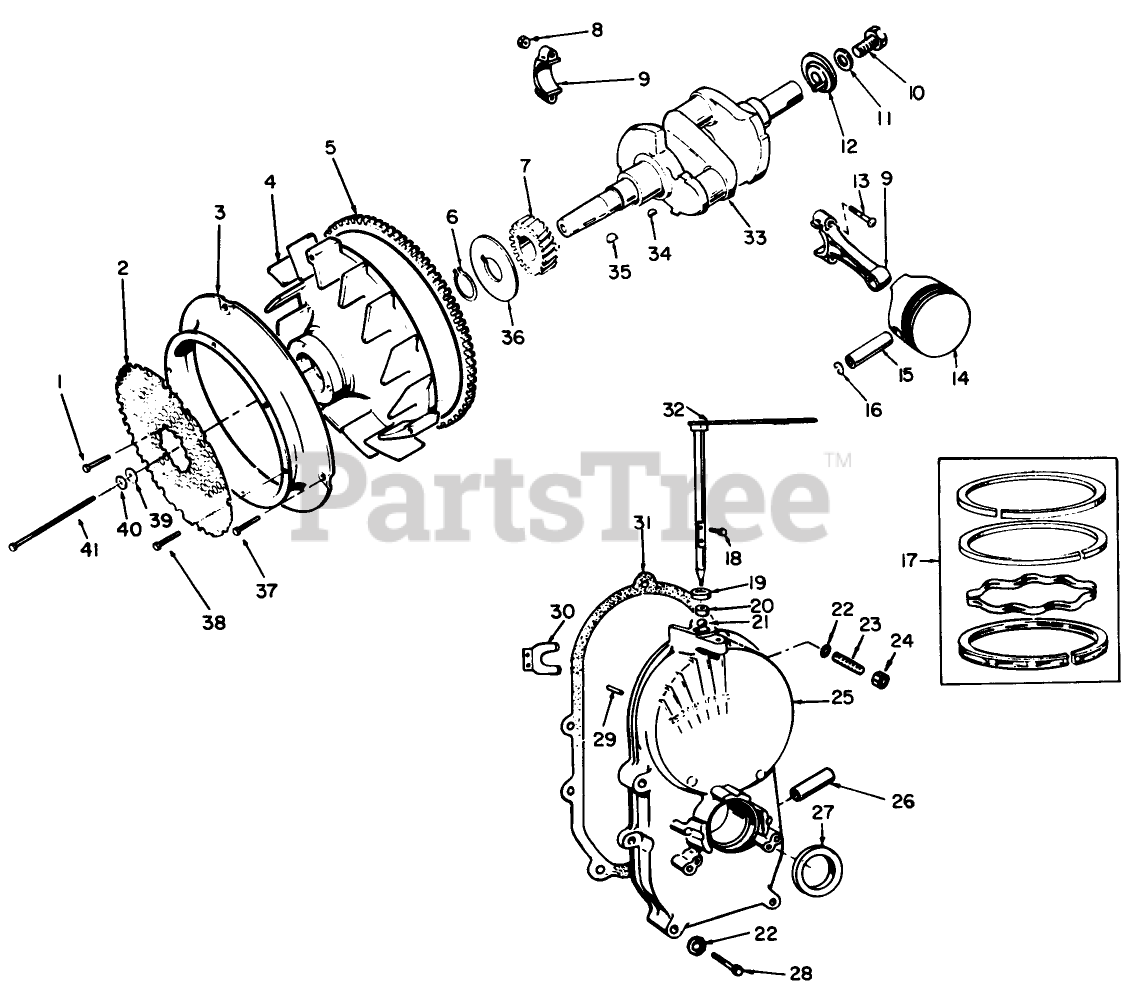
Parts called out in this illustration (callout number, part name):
1	Screw, Cap-Hex Head Locking
2	Guard, Flywheel
3	Venture, Blower Wheel
4	Flywheel (Incl. Ref. #5)
5	Gear, Ring
6	Ring Retaining
7	Gear Crankshaft
8	Nut, Hex-Crown Lock
9	Rod, Connecting-Standard (Incl. Ref. #8 13)
10	Screw, Cap Hex Hd.
11	Washer, Lock-Spring
12	SPACER
13	Bolt, Special-Connecting Rod
14	Piston and Pin-Standard (Incl. Ref. #15 16)
15	Pin, Piston
16	Ring, Retaining
17	Ring Set, Piston-Standard
18	Screw, Machine-Pan Hd.
19	Ball, Bearing-Governor Shaft
20	Bearing, Governor Shaft
21	Seal, Oil-Governor Shaft
22	Washer, Flat Copper
23	Stud, Gear Cover-Top Hole
24	Nut, Gear Cover Top Hole
25	Gear Case Assembly (Incl. Ref. #1 8-21, 23-24, 27-28 30)
26	Tube, Vacuum Port
27	Seal, Oil-Crankshaft
28	Screw Cap Hex Hd.
29	Pin, Dowel-Governor Cup Stop
30	Yoke, Governor Shaft
31	Gasket, Gearcase Mounting
32	Shaft and Arm, Governor
33	STRIP-BULB
34	Key Crankshaft Gear
35	Key Flywheel
36	Washer, Gear Retaining
37	Screw Cap Hex Washer Hd.
38	Screw Tapping Hex Washer Hd.
39	Washer, Flat
40	Washer, Lock-Spring
41	Screw, Cap-Hex Head
